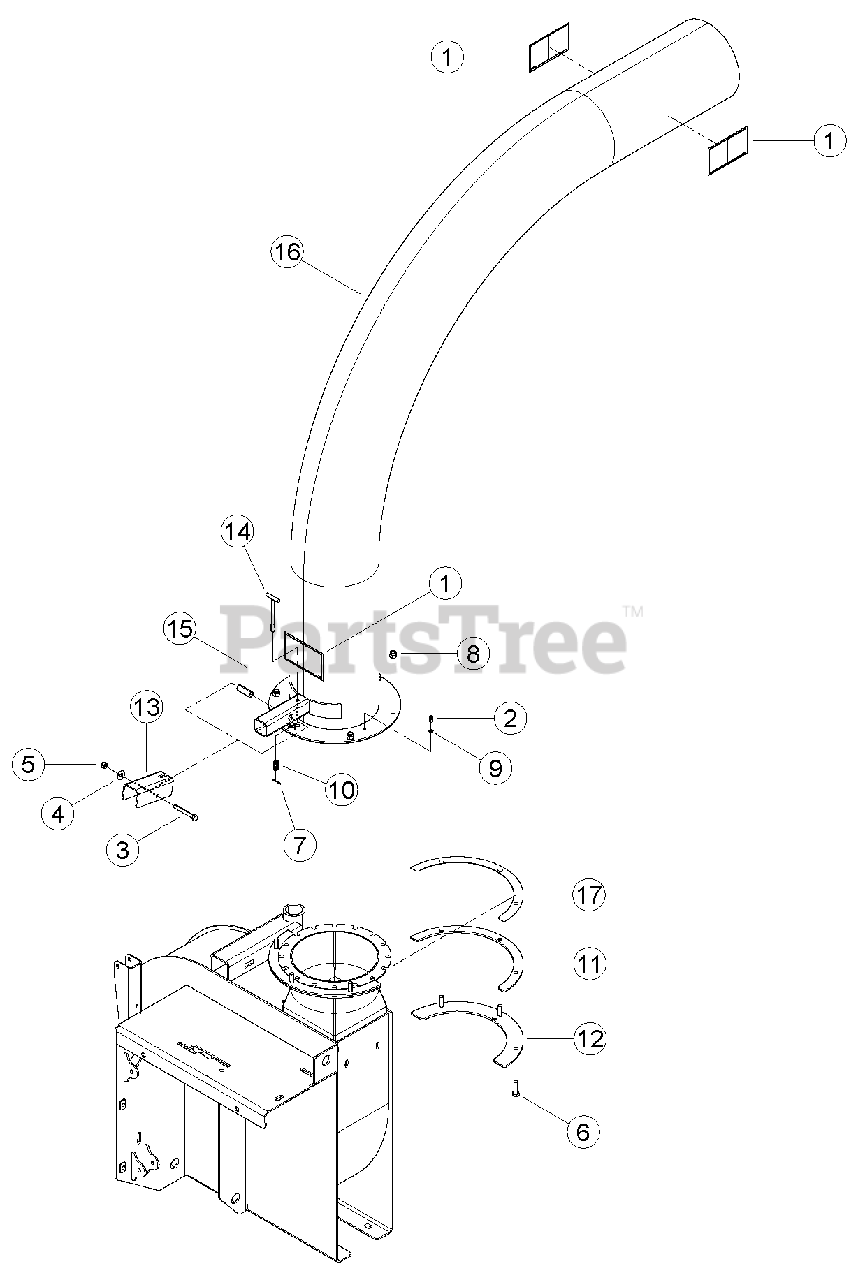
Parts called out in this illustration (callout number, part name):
1	DECAL, DISCHARGE ISO
2	FITTING, 1/4 SELF-TAP GREASE
3	BOLT, 5/16 X 2-1/2 HEX HD GR5 ZP
4	WASHER, 5/16 FLAT ZP
5	NUT, 5/16 NE NYLOCK ZP
6	BOLT, 3/8 X 1-1/4 HEX HD GR5 ZP
7	PIN, 3/32 X 3/4 COTTER
8	NUT, 3/8 NE NYLOCK ZP
9	WASHER, .254 X .400 X .048 FLAT
10	SPRING, LOCK COMPRESSION
11	RING, DISCHARGE SPACER
12	RING, DISCHARGE CLAMP
13	LEVER, DISCHARGE LOCK
15	TUBE, DISCHARGE LOCK PIVOT
16	WELDMENT, DISCHARGE TUBE
17	SHIM, DISCHARGE SPACER RING
